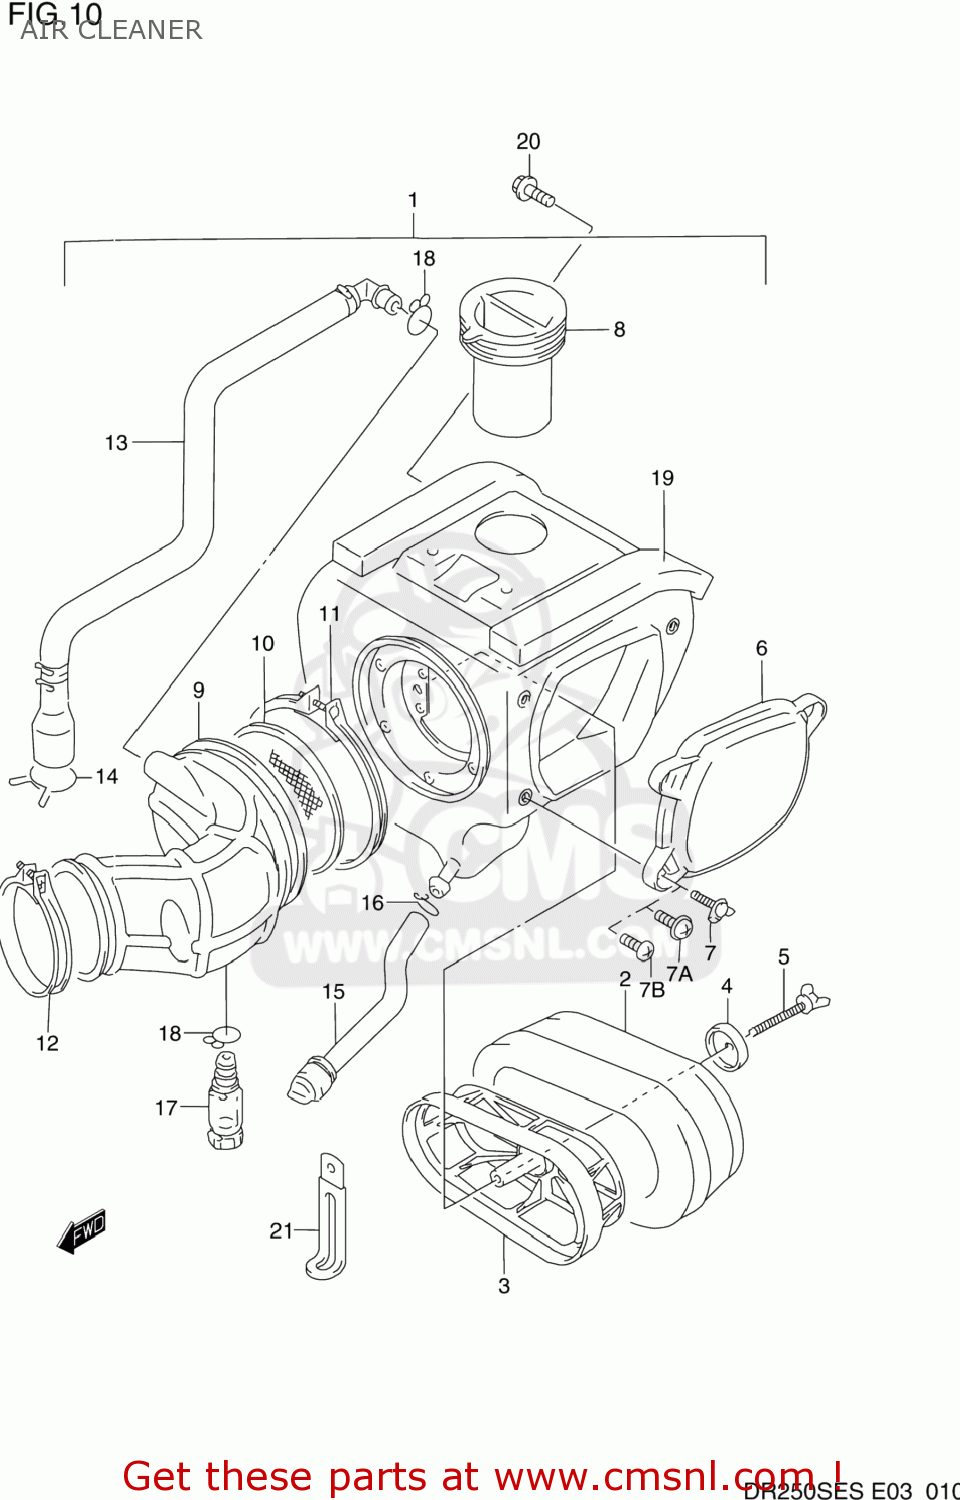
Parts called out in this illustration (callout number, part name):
1	CLEANER ASSEMBLY,AIR
2	FILTER
3	HOLDER,FILTER
4	WASHER,AIR CLEANER
5	BOLT,WING
6	CAP,AIR CLEANER
7	BOLT,WING
7A	SCREW
7B	SCREW
8	TUBE,INLET
9	TUBE,OUTLET
10	TRAP,FRAME
11	CLAMP
12	CLAMP
13	TUBE,BREATHER
14	CLIP
15	DRAIN TUBE
16	CLIP
17	TUBE,DRAIN
18	CLIP
19	CUSHION
20	BOLT
21	CLAMP
